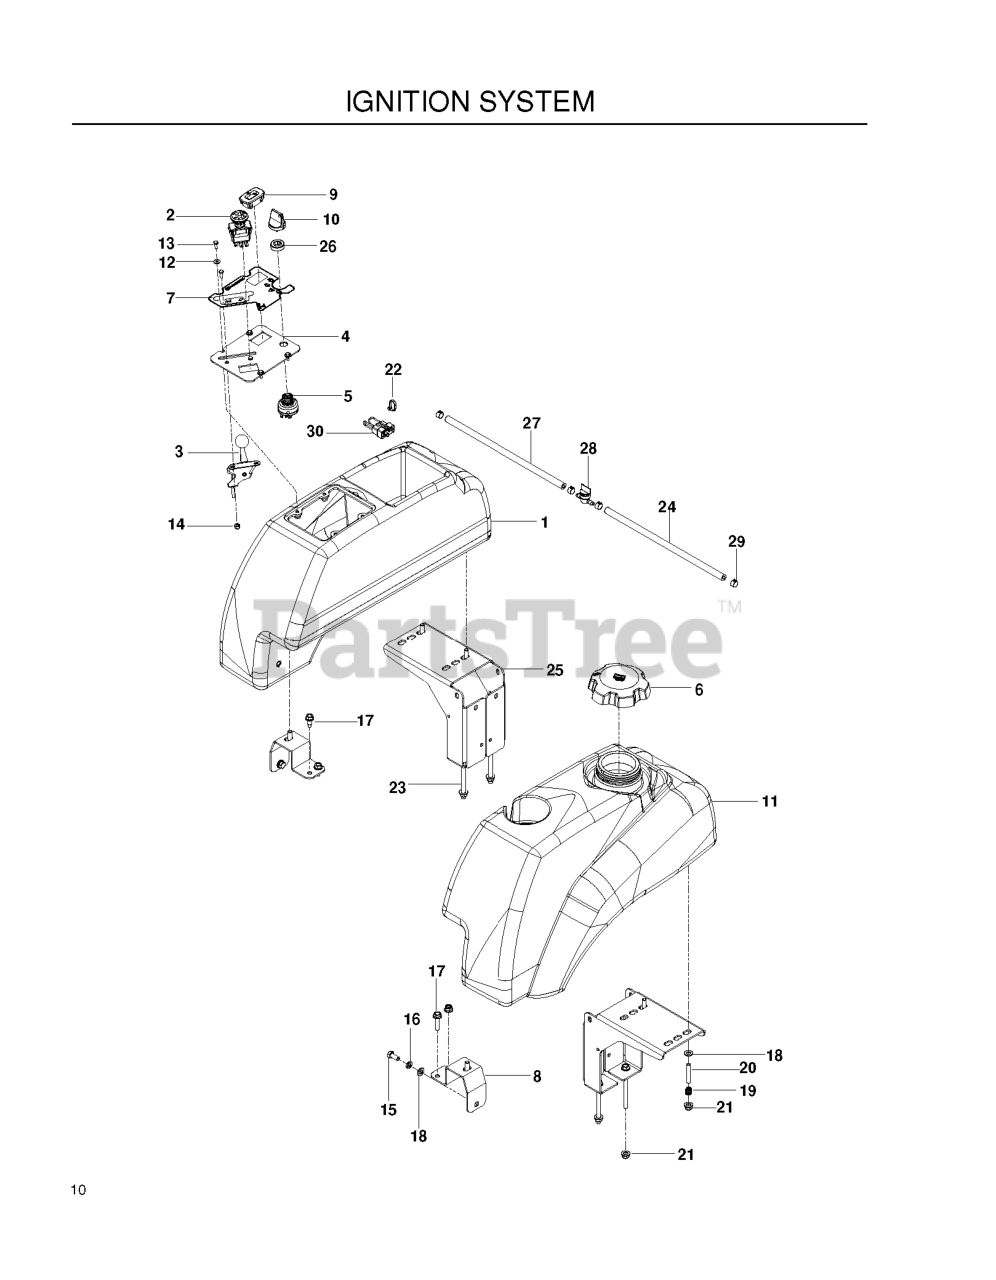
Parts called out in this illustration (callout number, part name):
1	FENDER CONSOLE
2	RP SWITCH.PTO.TERMINAL.STD.RED
3	THROTTLE CABLE
4	RP.PLATE, CONSOLE, BLK
5	SWITCH, IGNITION, INDAK
6	FUEL CAP, HTC
7	DECAL, CONSOLE
8	SUPPORT, TANK, BLK
9	HOUR METER
10	KEY, IGNITION
11	LEFT TANK W/CUP HOLDER
12	WASHER #10
13	HCS #10-24 X 1/2
14	NUT 10-24 NYLOC
15	HCS 5/16C X 3/4
16	WASHER.LOCK.HVY.HLCL.SPR.5/16
17	RP BLT 5/16-18 X 1 THRD FORM D
18	FLAT WASHER 5/16 SAE
20	STUD, 5/16C
21	5/16-18 NYLOC FLANGE NUT
22	TIE, PLASTIC
23	HHFS 5/16-18 X 3 3/4
24	FUEL LINE 18"
25	MOUNT, TANK, ZT BLK
26	CAP IGNITION NUT
27	FUEL LINE 13"
28	FUEL VALVE
29	HOSE CLAMP
30	PLUG, TIMER
